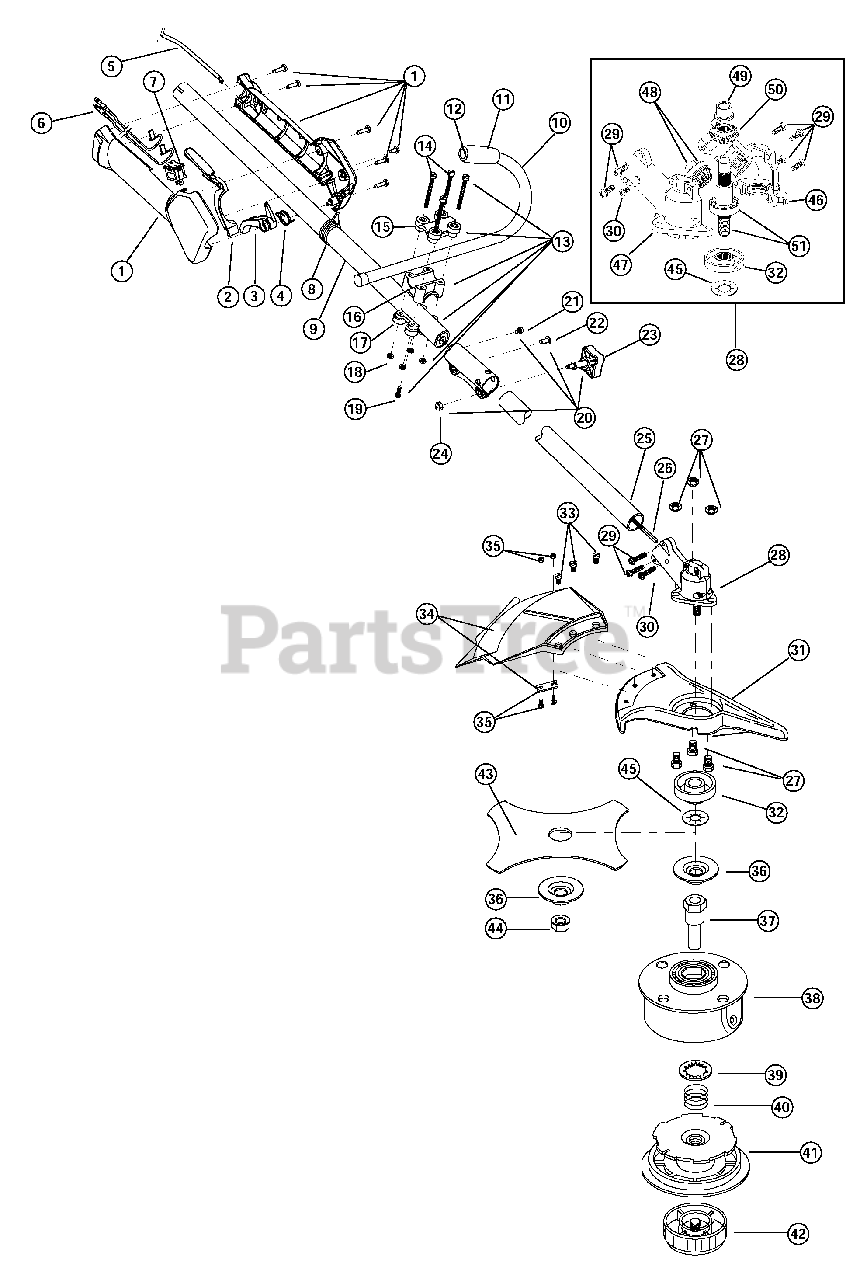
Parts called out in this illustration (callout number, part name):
1	Throttle Housing & Trigger Assembly
2	Throttle Trigger Lock-Out
3	Throttle Trigger
4	Throttle Trigger Spring
5	Throttle Cable Assembly
6	Lead Wire Assembly
7	Switch Assembly
8	Harness Clip
9	Upper Drive Shaft Housing Assembly
10	J-Handle Assembly
12	Tube Closure
13	Handle Bracket Assembly
15	Upper Handle Clamp
16	Middle Handle Clamp
17	Lower Handle Clamp
19	Anti-Rotation Screw
20	Click-Link Coupler
23	Adjustment Knob
24	Knob Retaining Nut
25	Lower Drive Shaft Housing Assembly
26	Lower Flexible Drive Shaft
27	Shield Mount Screw Assembly
28	2 piece Gearbox Assembly
29	Gearbox Mounting Hardware
30	Anti-Rotation Screw
31	Blade Shield/Shield Mount
32	Blade Driver
33	Shield Mounting Screw
34	Shield and Blade Assembly
35	Blade Assembly
36	Retaining Washer
37	Spool Shaft
38	Outer Spool Assembly
39	Retainer
41	Inner Reel
42	Bump Head Knob Assembly
43	4-Tooth Blade
44	Nut
45	Palnut
46	Left Housing
47	Right Housing
48	Pinion Gear Assembly
49	Output Shaft Bushing
50	Output Shaft Gear
51	Output Shaft Assembly
